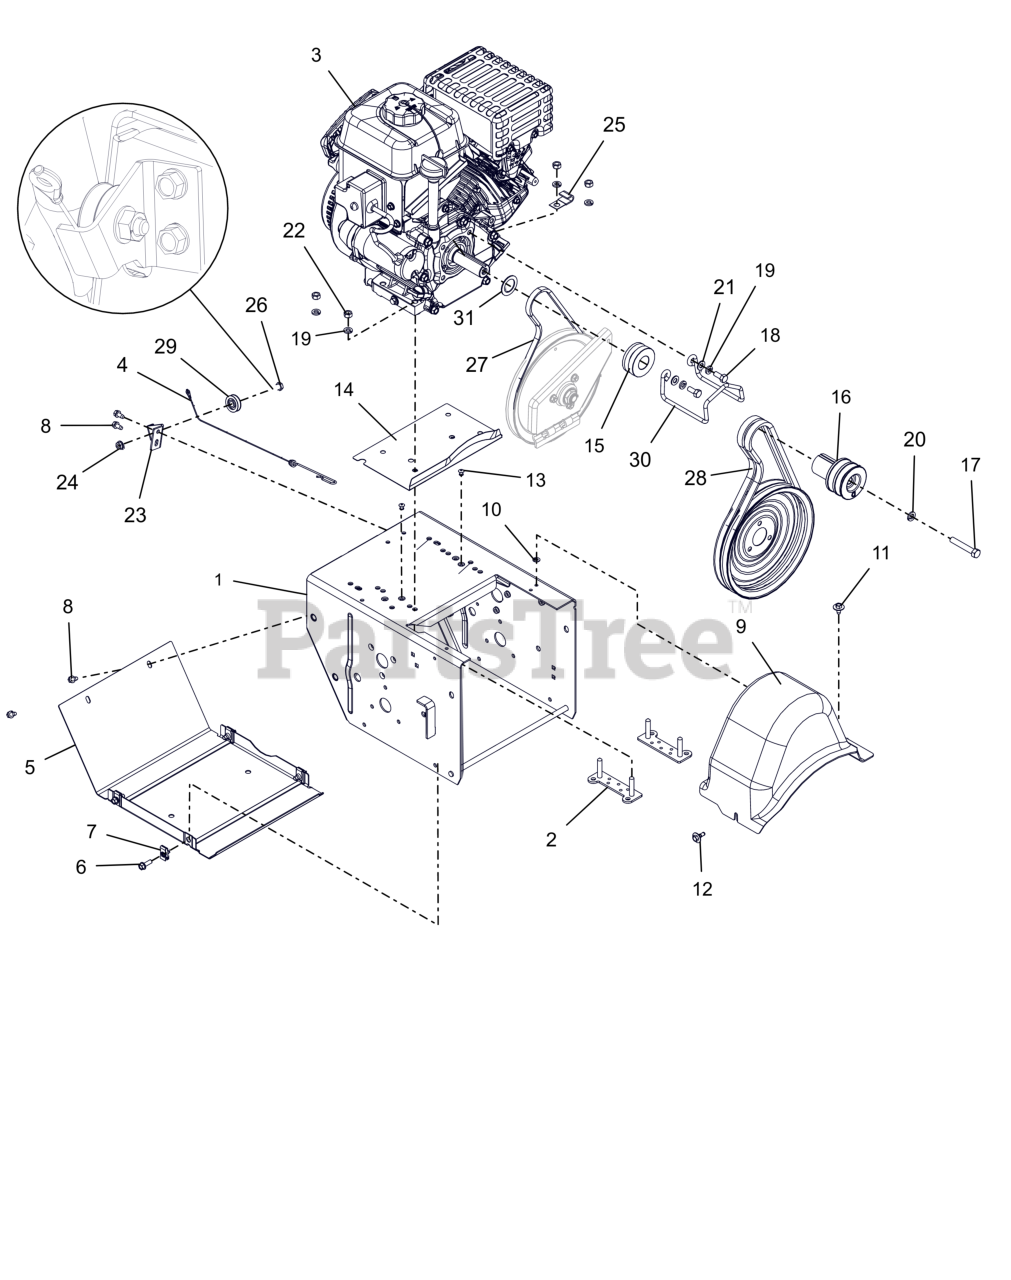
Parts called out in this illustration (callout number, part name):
1	FRAME, MAIN-DELUXE(WELDMENT)
2	STRAP, BOLT - SMALL ENGINE
3	ENGINE, AX254 GEN2 120V/60W
4	CABLE, LOWER TRACTION,SS & PRO
5	COVER, BOTTOM
6	BLT, HWH .25-20X.75 G5 ZCC
7	NUT-RTNR .25-20X.56
8	SCR-TAP .25-20X.50 HWH ZCC
9	COVER, BELT-SMALL
10	NUT-PUSH .25X.50 O.D.
11	SCR, TAP .25-20X.50 LG HWH ZCC
12	SCR-TAP .25-20X.5 CAPTIVE
13	RVT, POP .1875 ZCC
14	BAFFLE, WATER-SMALL
15	SHEAVE, TRACTION (KEYLESS)
16	SHEAVE,ATTACHMENT-STD 2 GRV
17	BLT, HEX .38-24X2.25 G5 ZCC
18	BLT, HEX .31-24X.750 G5 ZCC
19	WSHR, LK-HVY .312X.097 ZCC
20	WSHR,LK-REG .375X.094 ZCC
21	WSHR,FLT .344X.688X.065 ZCC
22	NUT, HEX .312-18 ZCC
23	BRACKET, CABLE PULLEY
24	NUT-LK-TOP-FLG .250-20 GF ZCC
25	J-CLAMP
26	BOLT, SHLDR -.375 X .375 X .25-20
27	V-BELT, 3L-WRAPPED
28	V-BELT, HA-RAW EDGE (SET)
29	PULLEY, CABLE
30	FINGER, BELT
31	WSHR, FLT 1.010X1.505X.062 ZCC
